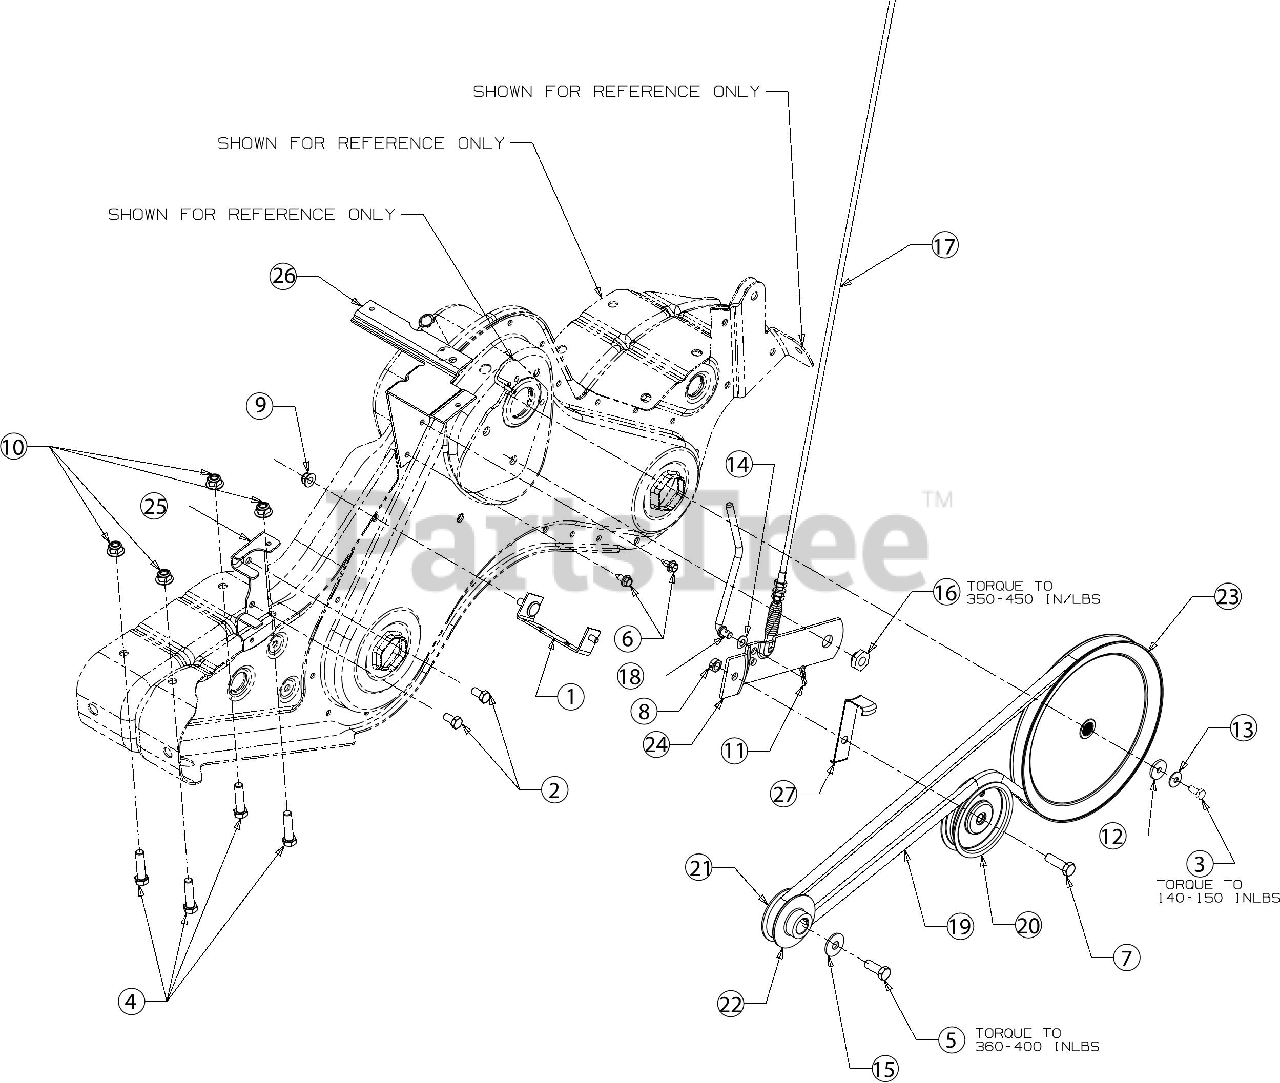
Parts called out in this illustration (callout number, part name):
1	BELT COVER BRACKET ASSEMBLY
1	WELD BOLT 5/16-18 X .875
2	HEX SCREW 5/16-24 X .62
3	BOLT 1/4-28 X .625 GR8
4	SCREW 3/8-16 X 1.50
5	SCREW 3/8-24 X 1.00 GR8
6	SCREW 1/4-20X.625
7	SCREW 3/8-16 X 1.25 GR5
8	JAM LOCK NUT
9	FLANGE LOCK NUT 5/16-18
11	COTTER PIN .072 DIA
12	FLAT WASHER
13	SPRING WASHER BELL
14	SPRING WASHER .317 X .625 X .020
15	BELL WASHER
16	SHOULDER NUT
17	CLUTCH CABLE
18	IDLER PULLEY ROD
19	BELT 1/2 X 58.16
20	IDLER PULLEY
21	ENGINE PULLEY INNER HALF
22	ENGINE PULLEY OUTER HALF
23	INPUT PULLEY
24	IDLER BRACKET
25	BELT KEEPER BRACKET
26	SHIFT COVER BRACKET
27	IDLER BELT KEEPER
